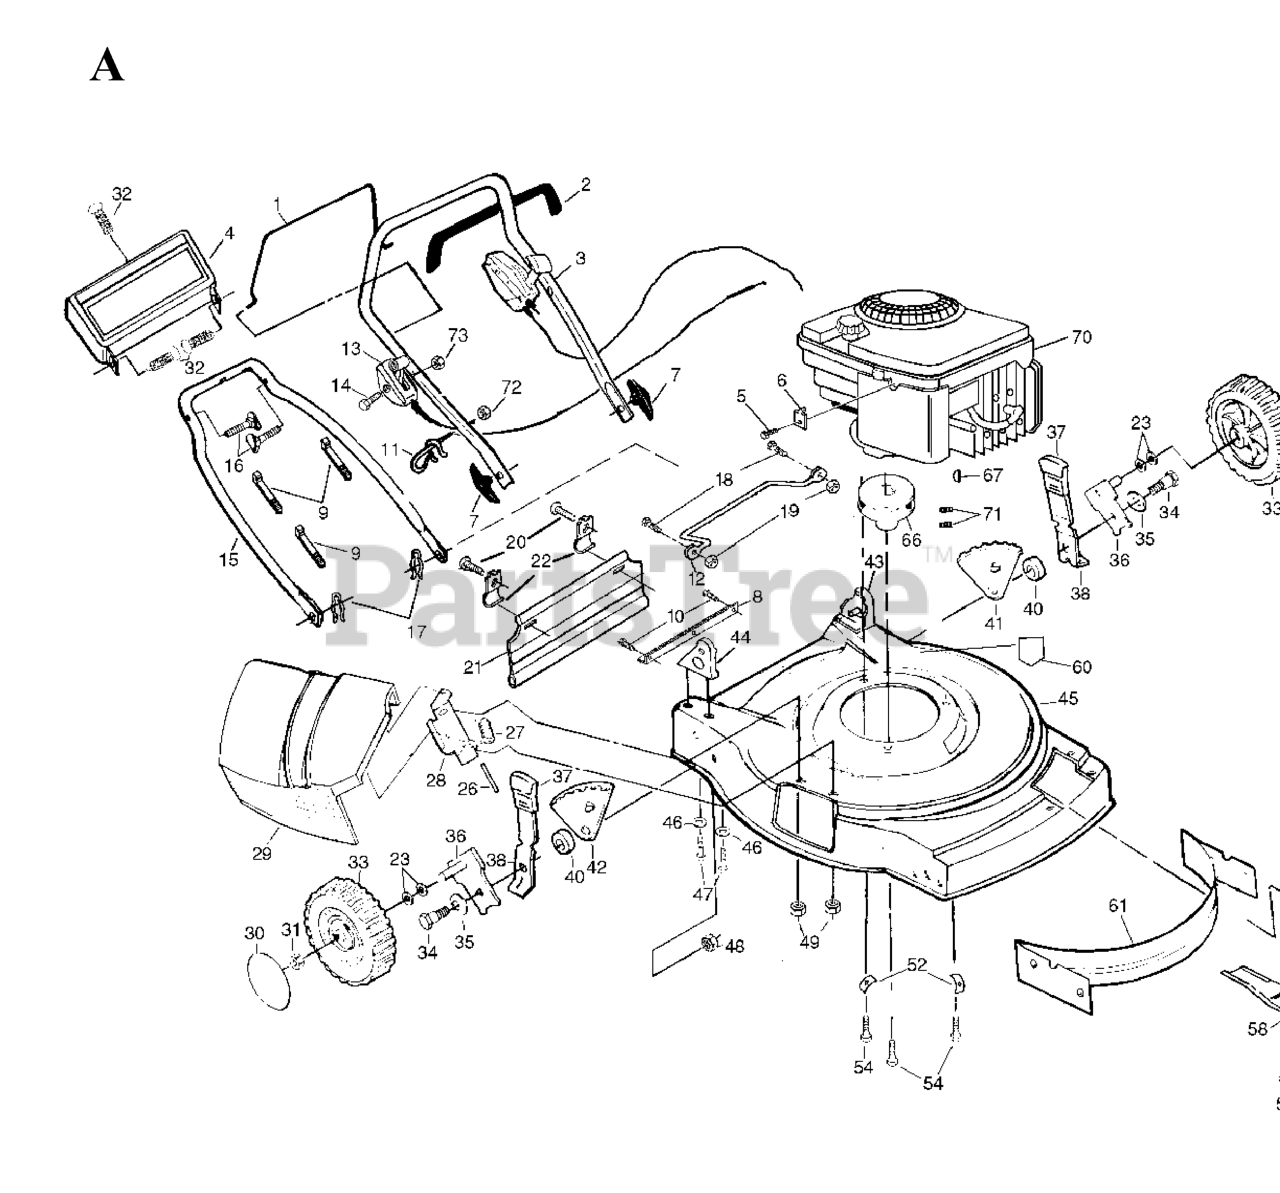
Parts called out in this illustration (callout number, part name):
1	CONTROL BAR
2	HANDLE GRIP
3	UPPER HANDLE
4	TRIM PLATE
5	SCREW.HEX.HEAD.WASHER.10-16
6	WASHER
7	HANDLE KNOB
9	CLIP CABLE SNAP
11	ROPE GUIDE
13	THROTTLE CONTROL
14	SCREW 1/4-20X1.75
15	HANDLE, LOWER
16	HANDLE BOLT
17	HAIRPIN COTTER
20	TAPPING SCREW
21	REAR SKIRT
22	BRACKET DEFL PM
23	WAVE WASHER
24	REPL BY 817 02 10-08
26	ROD.HINGE.COMBI-C
28	BRACKET PM
29	DISCHARGE GUARD
31	HEX FLANGE LOCKNT
33	WHEEL.8X2.PR.LP.RAD.GREY
34	BOLT
35	WASHER.BELLEVILLE (3 2 LB)
36	AXLE ARM
37	SELECTOR KNOB
40	RP SPACER HT ADJ
41	WHL ADJ BRKT RF/LR
42	WHL ADJ BRKT LF/RR
43	HDLE BRKT ASSY LH
44	HDLE BRKT ASSY RH
47	SCREW.5/16-18X3/4
48	LOCKNUT PM
49	NUT
52	WASHER.ENGINE.BZP
53	DEBRIS SHIELD
54	BOLT 3/8-16X1-1/8
55	SCREW, HEX HD 3/8-24 X 1-3/8
56	LOCKWASHER
57	WASHER,HARDEN
59	BLADE ADAPTOR
60	DECAL MOWER CUT/FINGER
66	ENGINE.PULLEY.FWG
67	HI PRO KEY PM WSL
72	NUT
73	NUT
